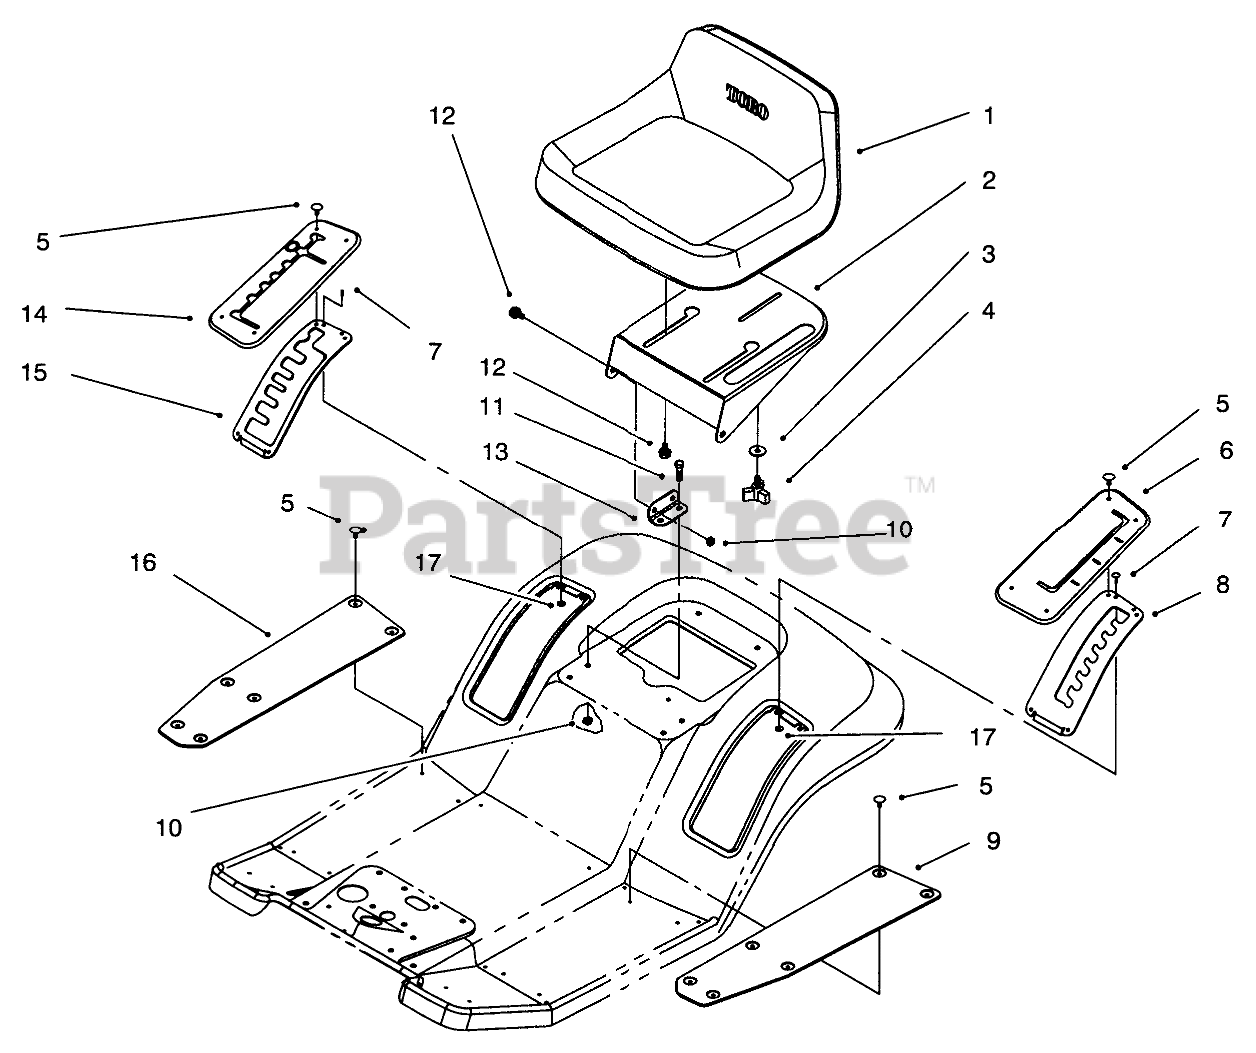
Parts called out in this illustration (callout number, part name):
2	Support-Seat
3	WASHER-PIVOT
5	FASTENER-PANEL
6	COVER-HOC
7	RIVET-BLIND
8	Gate-H.O.C.
9	MAT-FOOT, LH
10	NUT-LOCK, NI
11	SCREW-HH
12	BOLT-SHOULDER
13	Bracket-Seat Hinge
14	COVER-GATE, SHIFT
15	Gate-Shift
16	MAT-FOOT, RH
17	WASHER-PLAIN
